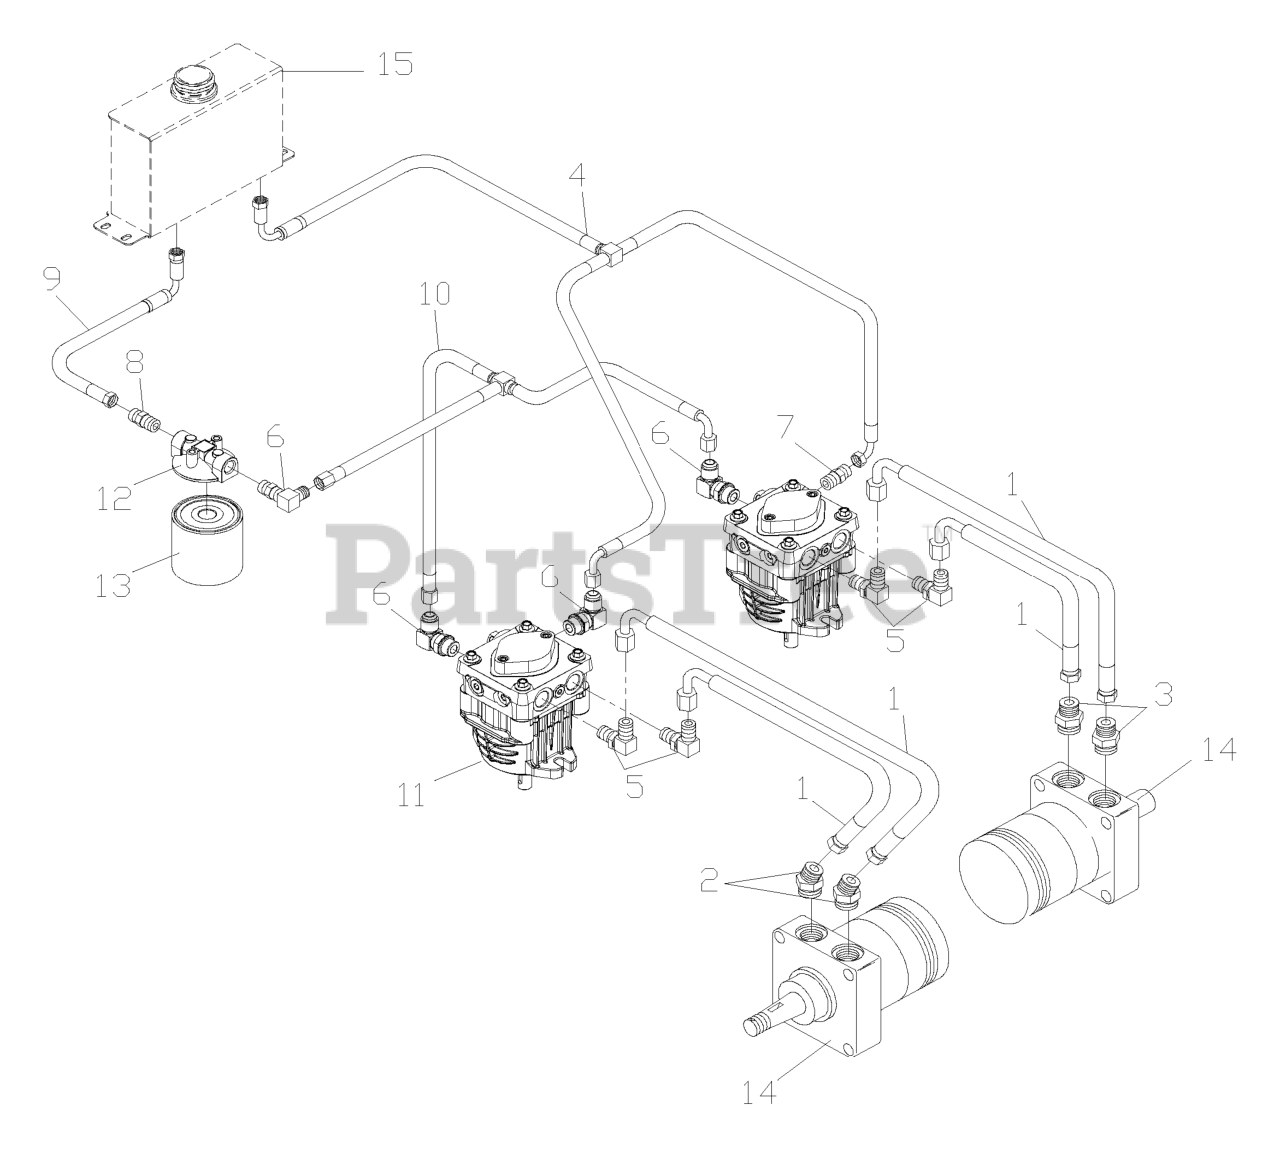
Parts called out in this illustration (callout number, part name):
1	HOSE, 1/2" HYDRAULIC
2	ELBOW-ADJ 45 DEG F6802-8-10
3	CONNECTOR, STRAIGHT
4	INLET TEE HOSE
5	ELBOW, 90 DEGREE
6	ELBOW, F6801-6-6-0 90 DEGREE
7	FITTING, STRAIGHT F6400-6-4-0
8	STRAIGHT FITG
9	HOSE
10	RETURN TEE HOSE
11	HG_PUMP
12	FILTER HEAD
13	HYDRAULIC OIL FILTER
14	WHEEL MOTOR
14	SEAL KIT - GEN I
15	OIL TANK BLK
